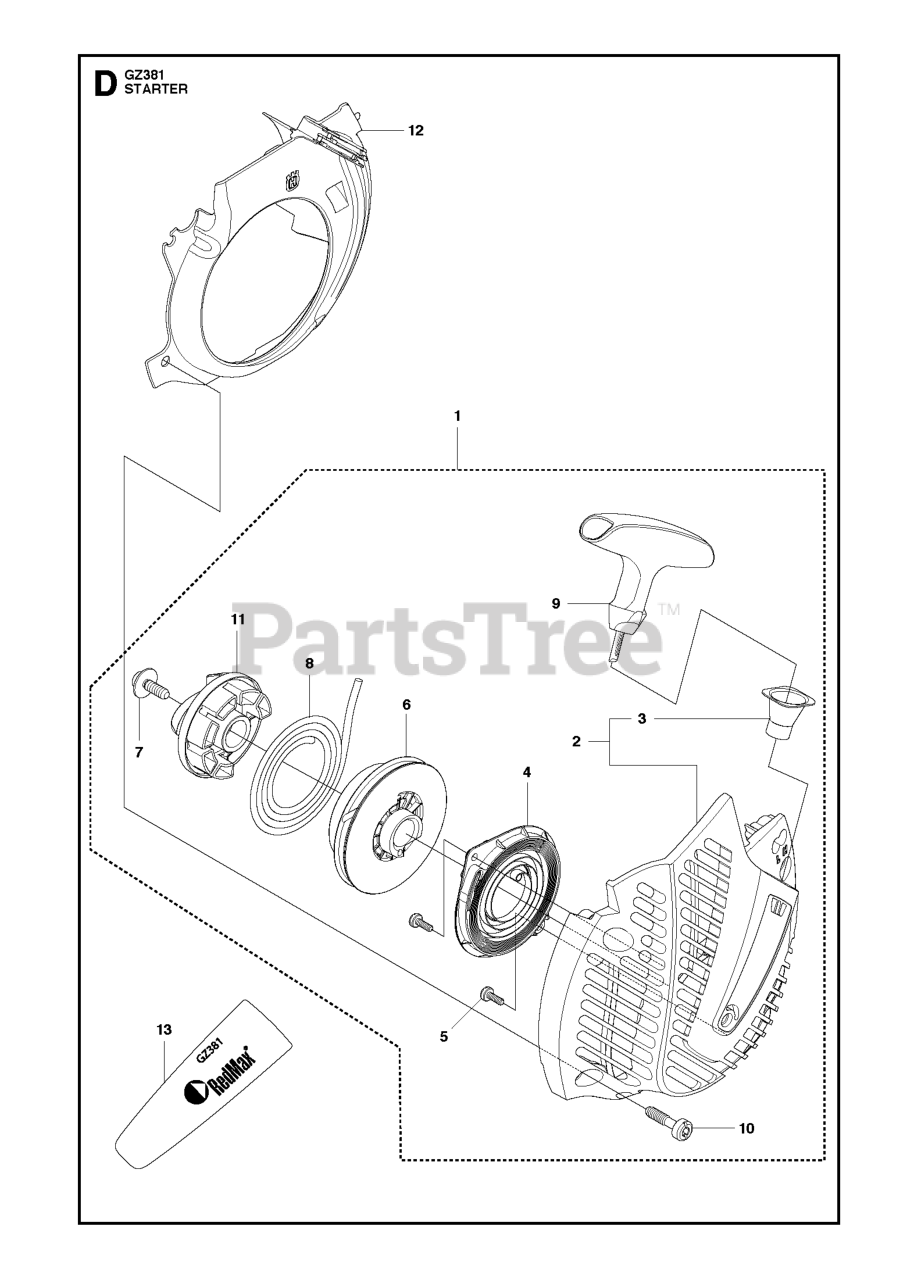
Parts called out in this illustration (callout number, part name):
1	ASSY STARTER
2	HOUSING FAN JONSERED
4	SPRING CASSETTE ASSY
5	SCREW CCRPANT
6	STARTER PULLEY
8	STARTER CORD
9	STARTER HANDLE
12	COOLING AIR CONDUCTOR
13	LABEL STARTER STANDARD GZ381
